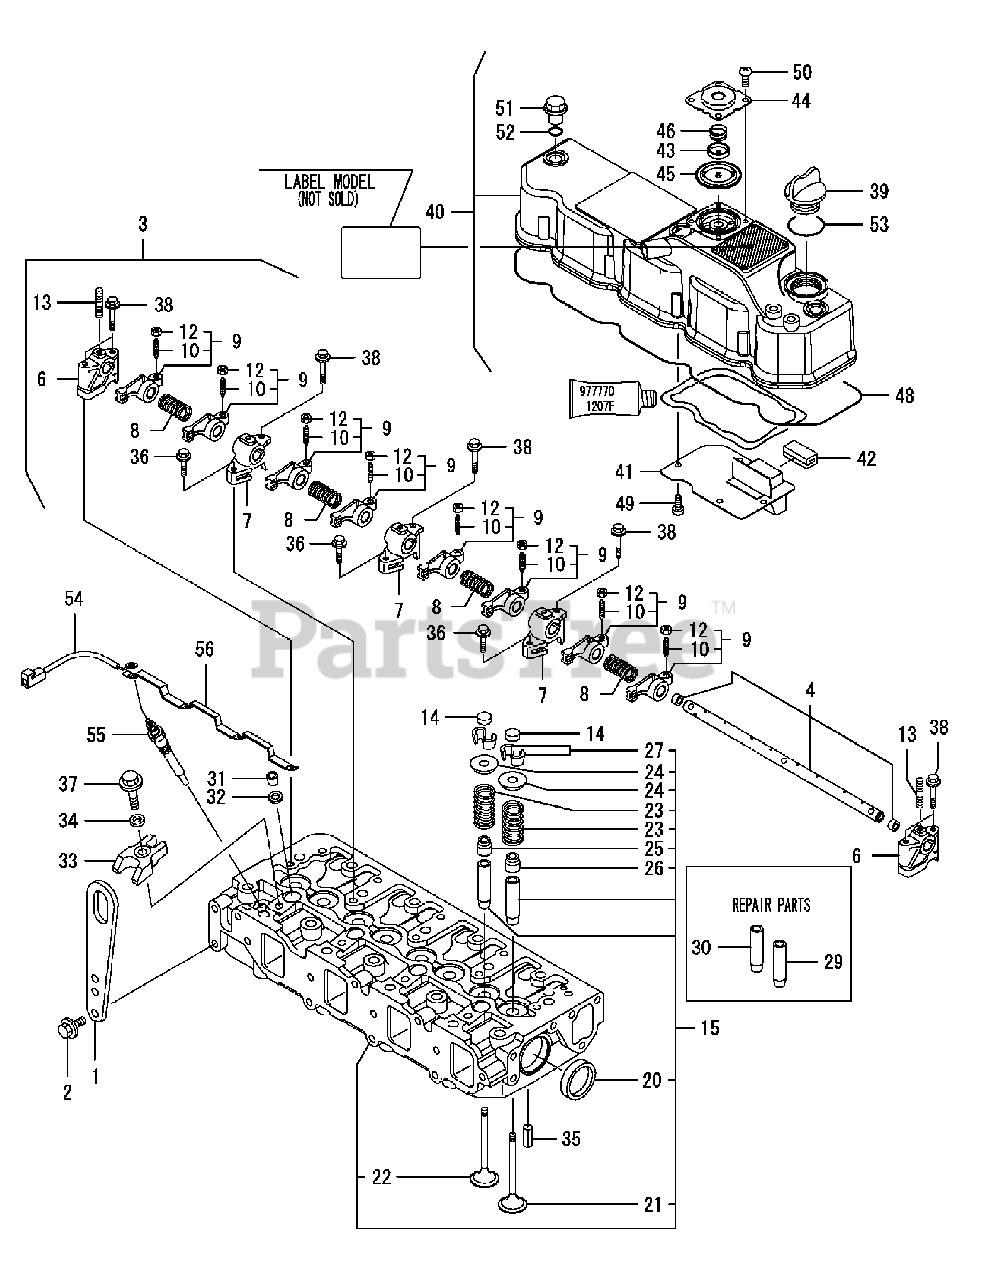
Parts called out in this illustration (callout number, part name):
1	LIFTER, ENGINE
2	BOLT 8X 14 PLATED
3	SHAFT ASSY, ROCKER
4	SHAFT, ROCKER ARM
6	SUPPORT, ARM A
7	SUPPORT, ARM B
9	ARM KIT, ROCKER
10	SCREW, VALVE ADJUST
13	STUD M 8X 18 PLATED
15	HEAD ASSY, CYLINDER
22	VALVE, EXHAUST
24	RETAINER, SPRING
25	SEAL, VALVE STEM
26	SEAL, VALVE STEM
30	GUIDE, EXHAUST VALVE
31	PROTECTOR, NOZZLE
33	RETAINER, NOZZLE
34	WASHER, INJECTOR
35	SPRING PIN 6X12
36	BOLT M 8X 25 PLATED
37	BOLT M 8X 35 PLATED
38	BOLT M 8X 50 PLATED
40	BONNET ASSY, HEAD
42	BAFFLE, BREATHER
44	COVER, DIAPHRAGM
46	SPRING, DIAPHRAGM
48	GASKET, BONNET
52	PACKING, P 12.0
53	O-RING 1A P-32.0
54	HARNESS, GLOW PLUG
56	CONNECTOR, GLOW PLUG
